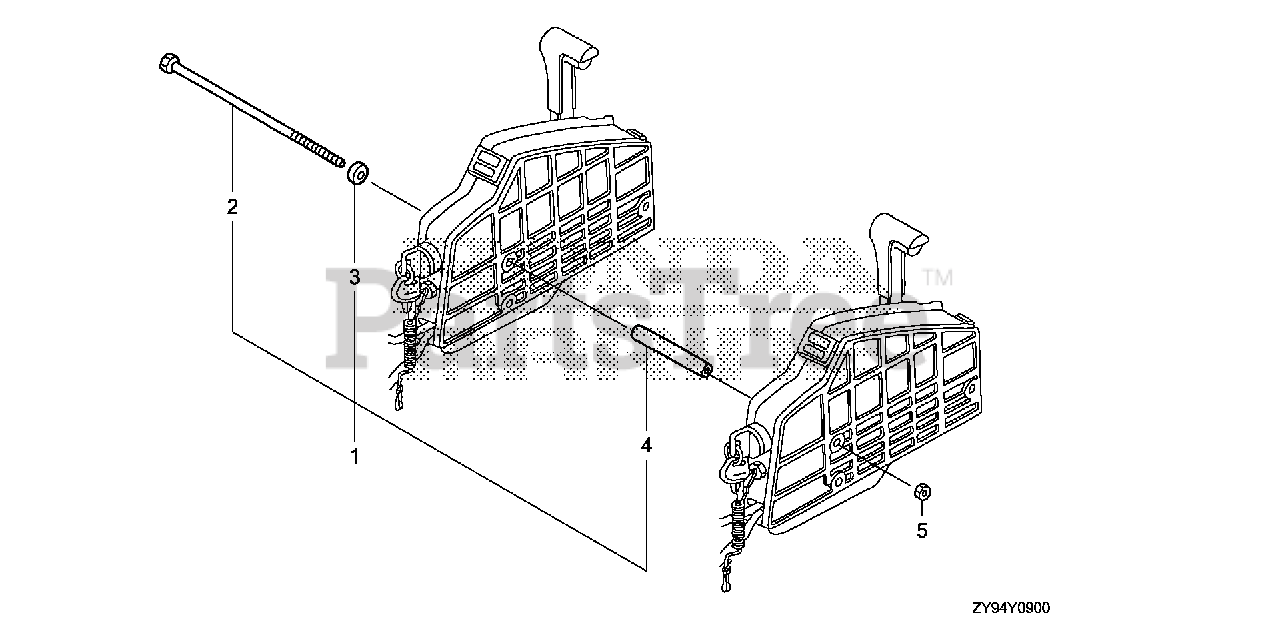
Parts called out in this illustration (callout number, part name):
1	BOLT KIT, SIDE REMOTE CONTROL
2	BOLT, SPECIAL (6X220)
3	COLLAR, DISTANCE (A)
4	COLLAR, DISTANCE (B)
5	NUT, HEX. (6MM)
